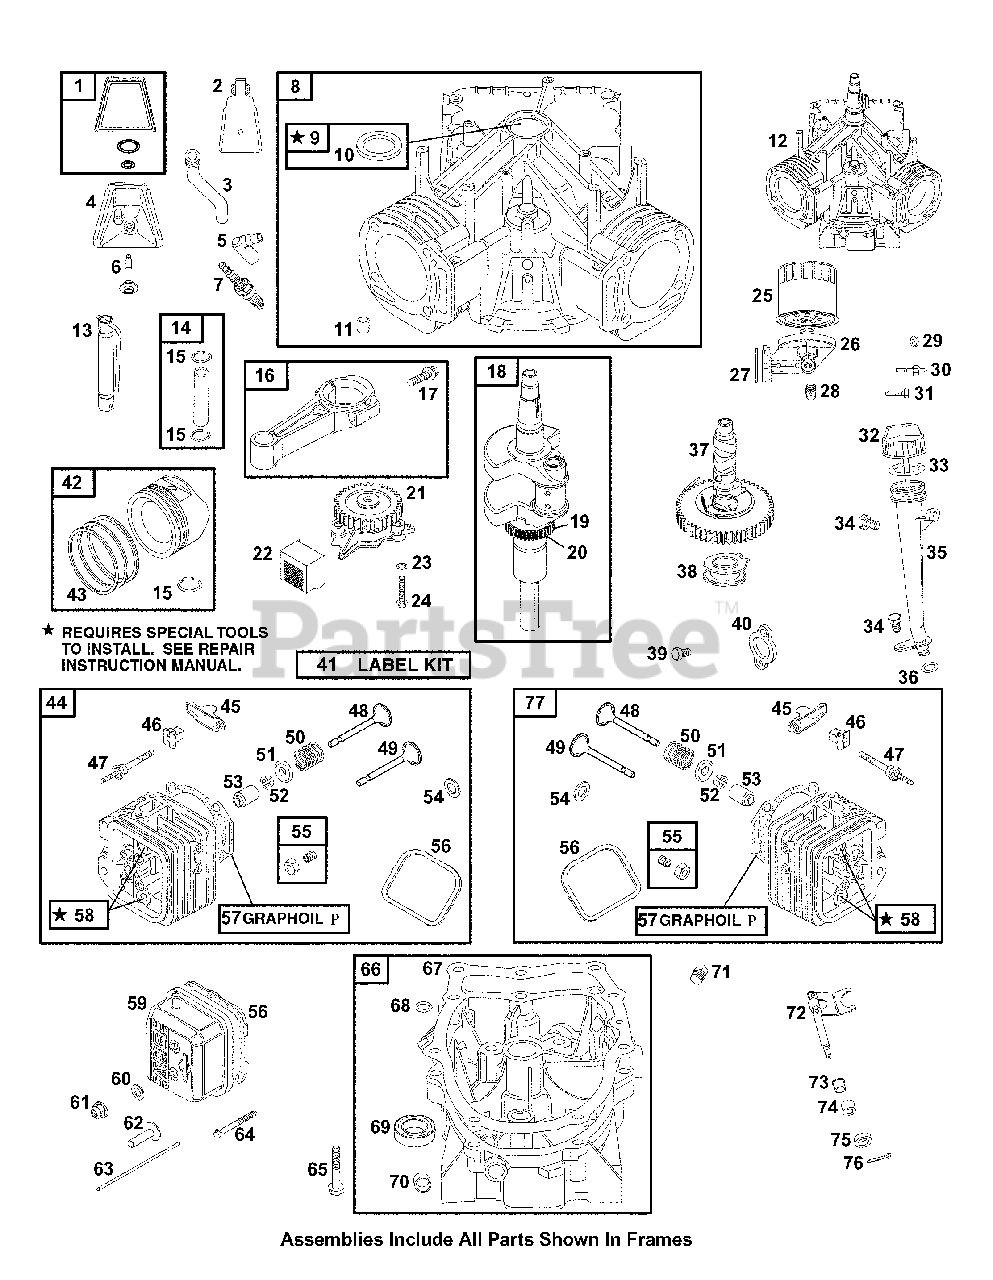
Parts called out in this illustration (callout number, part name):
1	Breather Gasket
2	Breather Baffle
3	Breather Tube
4	Breather Assembly
5	Sparkplug Boot
6	Screw (Breather Assembly)
7	Sparkplug
9	Bushing/Seal Kit
10	Oil Seal
11	Locating Pin
12	Short Block
13	Sparkplug Wrench
14	Piston Pin
15	Piston Pin Lock
16	Connecting Rod (Standard)
17	Screw (Connecting Rod)
18	Crankshaft
19	Timing Key
20	Timing Gear
22	Oil Pump Screen
23	O-Ring Seal (Oil Pump)
24	Screw (Oil Pump)
25	Oil Filter
26	Oil Filter Adapter
27	Oil Adapter Gasket
28	Oil Drain Plug
29	Washer (Oil Filter Adapter)
30	Stud (Oil Filter Adapter)
31	Screw (Oil Filter Adapter)
33	O-Ring Seal (Dipstick)
34	Screw (Dipstick Tube)
35	Dipstick Tube
36	O-Ring Seal (Dipstick Tube)
37	Camshaft
38	Governor Spool
39	Screw (Exhaust Manifold)
40	Exhaust Gasket
42	Piston Assembly (Standard)
43	Ring Set (Standard)
44	Cylinder Head #1
45	Arm Rocker
46	Arm Rocker Pivot
47	Rocker Arm Stud
48	Intake Valve
49	Exhaust Valve
50	Valve Spring
51	Valve Retainer
52	Valve Keeper
53	Valve Seal
54	Sealing Washer
55	Rocker Arm Adjuster
56	Rocker Cover Gasket
57	Cylinder Head Gasket
58	Guide Bushing
59	Rocker Cover
60	Sealing Washer (Carburetor Plug)
61	Nut (Rocker Cover)
62	Valve Tappet
63	Push Rod (Steel)
64	Screw (Cylinder Head)
65	Screw (Engine Sump)
66	Engine Sump
67	Crankcase Gasket
68	O-Ring Seal
69	Oil Seal
70	Washer (Governor Crank)
71	Oil Drain Plug
72	Governor Crank
73	Governor Crank Bushing
74	Governor Crank Bushing
75	Governor Shaft Seal
76	Governor Shaft Retainer
77	Cylinder Head #2
